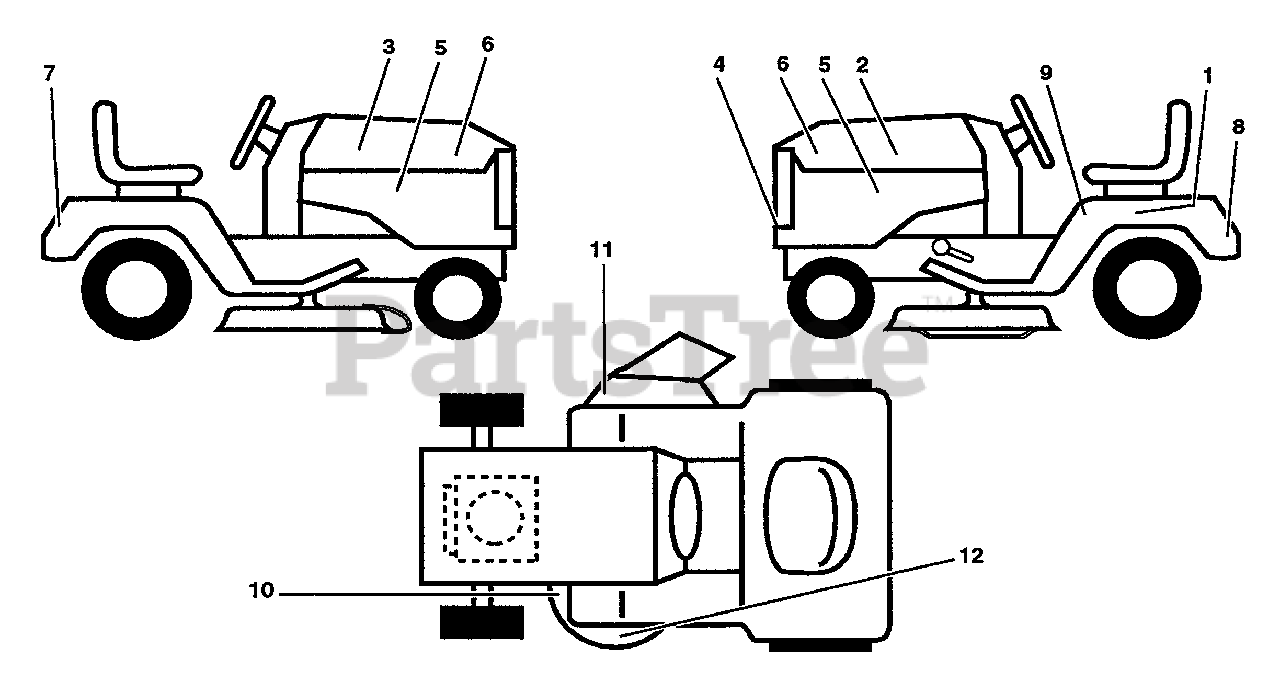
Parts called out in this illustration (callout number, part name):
1	Decal, Caution, Battery
2	Decal, Stripe, R.H. Hood
3	Decal, Stripe, L.H. Hood
4	Decal, Grill
5	Decal, Side Panel
6	Decal, Hood
7	Decal, Logo, Fender
8	Decal, Certification
8	Decal, 100 DBA
9	Decal, Instruction, Warning,
10	Decal, Caution, Deflector,
11	Decal, Warning, Cut Finger,
12	Decal, Rotating Blades,
12	Sheet, Instruction, Tractor, 15 Degree Slope,
12	Manual, Operator's
